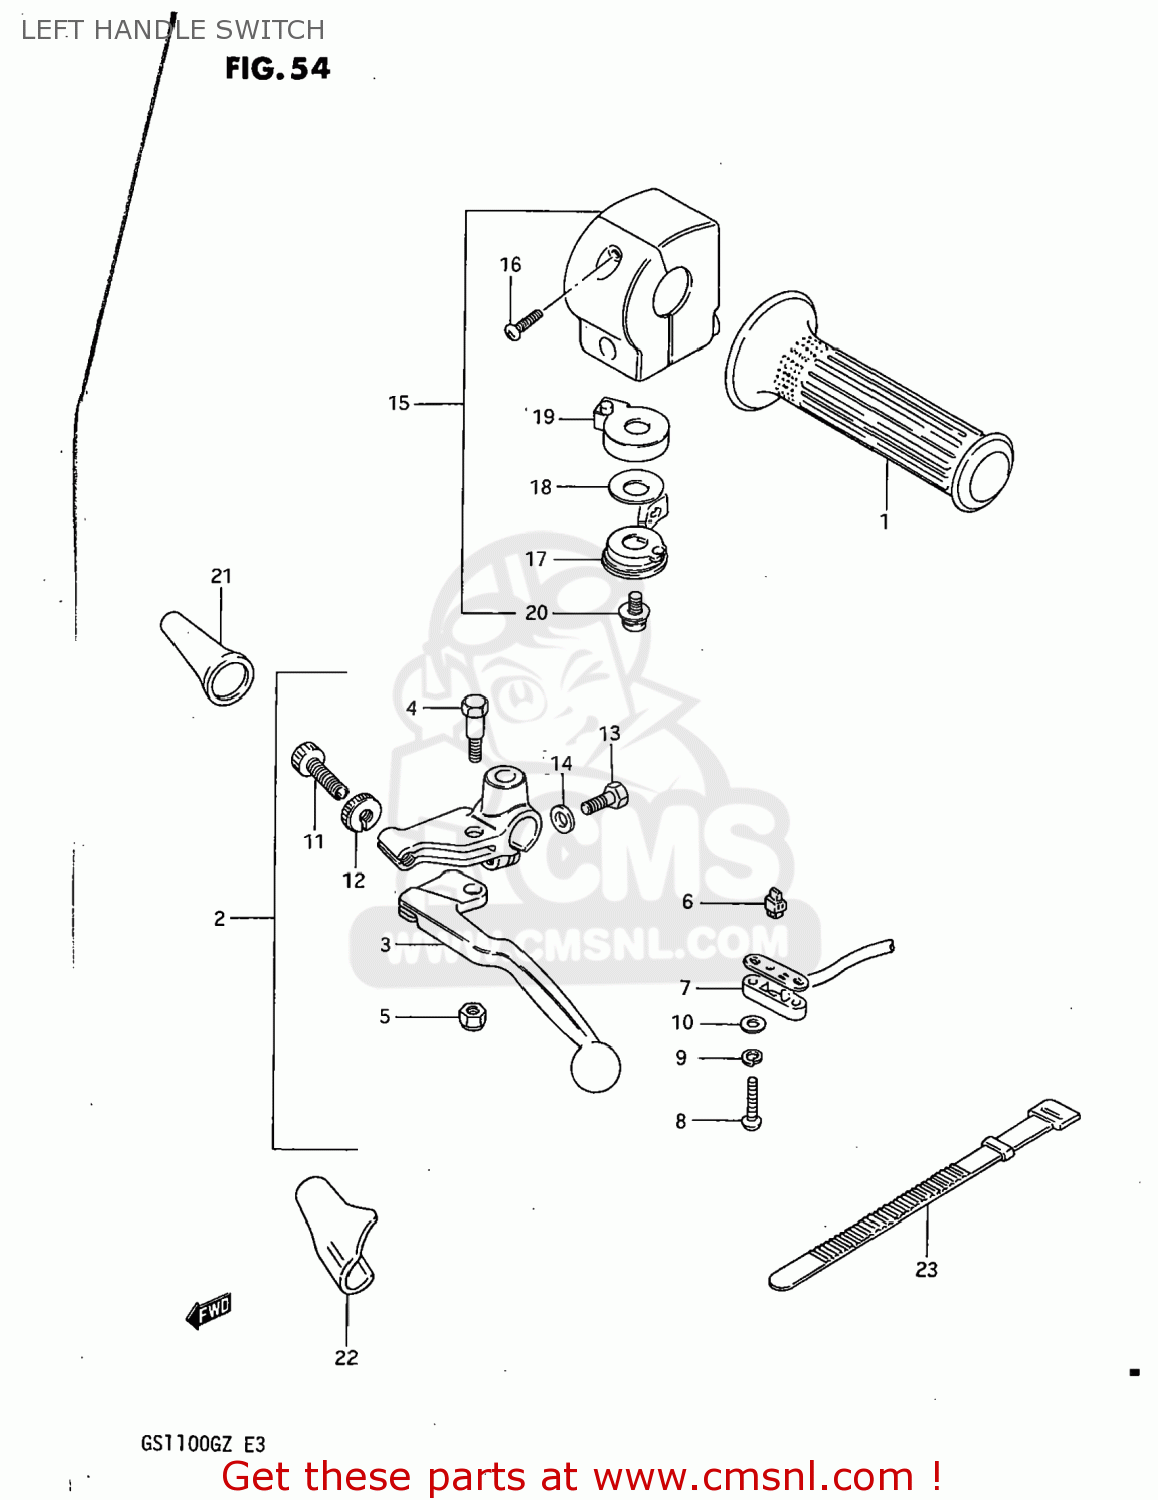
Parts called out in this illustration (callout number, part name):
1	GRIP,LEFT
2	LEVER ASSEMBLY
3	LEVER,CLUTCH
4	BOLT,LEVER
5	NUT 6MM
6	CONTACT,SWITCH
7	COVER,FR BK TERMINAL BASE
8	SCREW
9	LOCK WASHER
10	WASHER
11	ADJUSTER,CABLE
12	NUT,CABLE ADJUSTER
13	BOLT,CLUTCH LEVER HOLDER
14	WASHER
15	SWITCH ASSEMBLY,HANDLE,LEFT
16	SCREW
17	LEVER,STARTER
18	WASHER,ADJUSTER
19	BODY,CHOCK
20	SCREW,CHOKE LE
21	BOOT,CLUTCH CABLE
22	COVER,CLUTCH LEVER
23	CLAMP(L:120)
